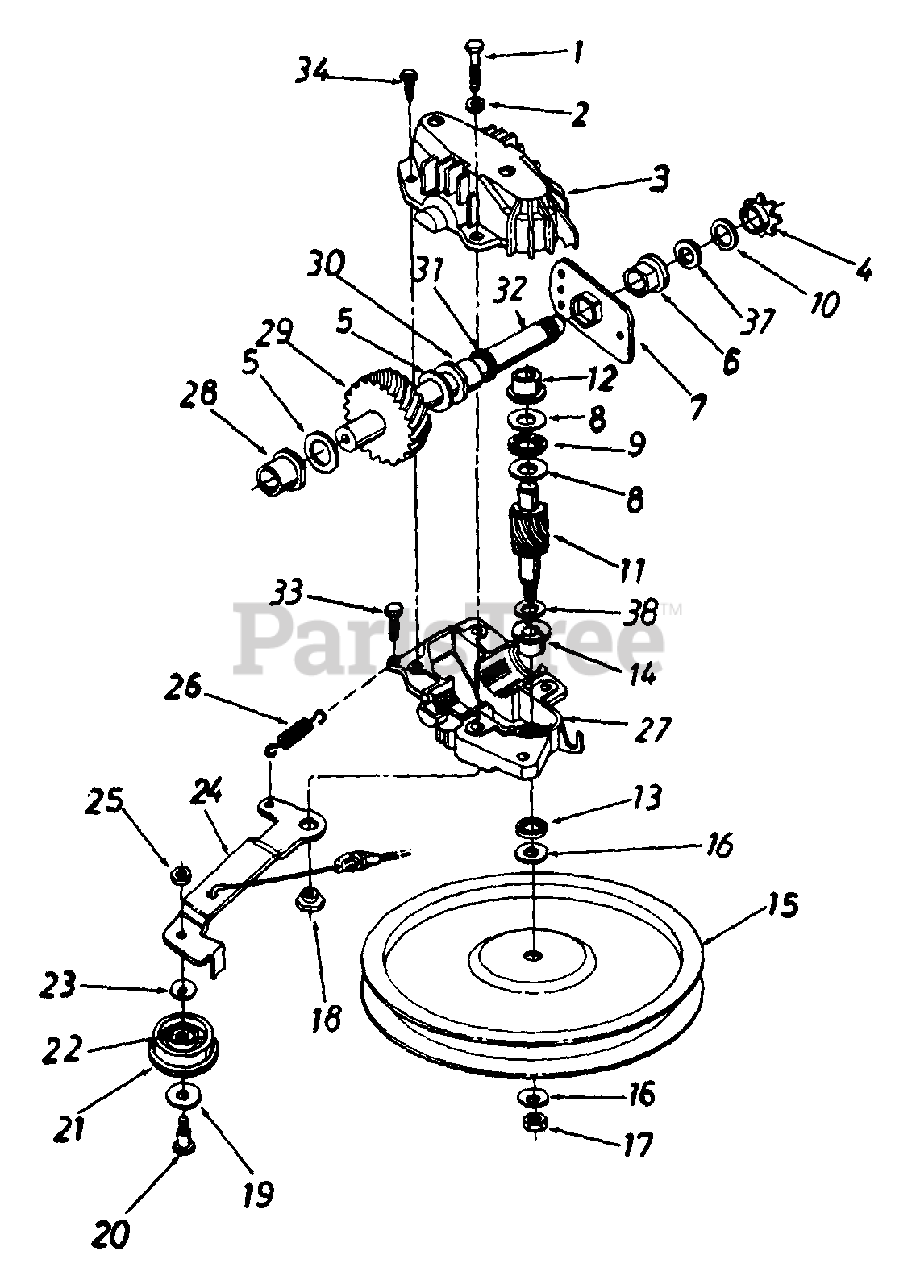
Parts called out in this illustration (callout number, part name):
1	Hex Bolt 1/4-20 x 1.25" Lg. w/Patch
2	L-Wash. 1/4" I.D.
3	Upper Hsg. Half
4	#48 Sprocket 6 Tooth x 1/2" Pitch
5	Fl-Wash. 5/8" I.D. x .03" Thk.
6	Hex Flange Bearing .506" I.D.
7	Bearing Bracket
8	Thrust Wash. .382" I.D. x .70" O.D.
9	Thrust Brg. .375" I.D. x .812" O.D.
10	Fl-Wash. 7/16" I.D. x .75" O.D.
11	10 Tooth Pinion Shaft
12	Flange Bearing
13	Oil Seal
14	Flange Brg. .503" I.D.
15	Fl-Pulley 5.06" O.D.
16	Bell-Wash. .325" I.D. x .93" O.D.
17	Hex Jam Nut 5/16-24 L.H. Thd.
18	Shld. Spacer .375" I.D. x .165"
19	Fl-Wash. .390" I.D. x 1" O.D.
20	Shld. Bolt .375" Dia. x .4"
21	Idler Pulley Ass'y.
23	Bell-Wash. .265" I.D. x .75"
24	Idler Brkt. Ass'y.
25	Hex Nut 1/4-28 Thd.
26	Ext. Spring 1.12" Lg.
27	Lower Hsg. Half
28	Flange Bearing .566" Dia.
29	34 Tooth Helical Gear
30	Flange Bearing .629" Dia.
32	Gear Sprocket Shaft
33	Hex Hd. Tap Scr. #10-16 x .75" Lg.
34	Hex B-Tap Scr. #10 x .62" Lg.
37	Fl-Wash. 1/2" I.D. x 1" O.D.
38	Fl-Wash..504" I.D. x .7" O.D.
